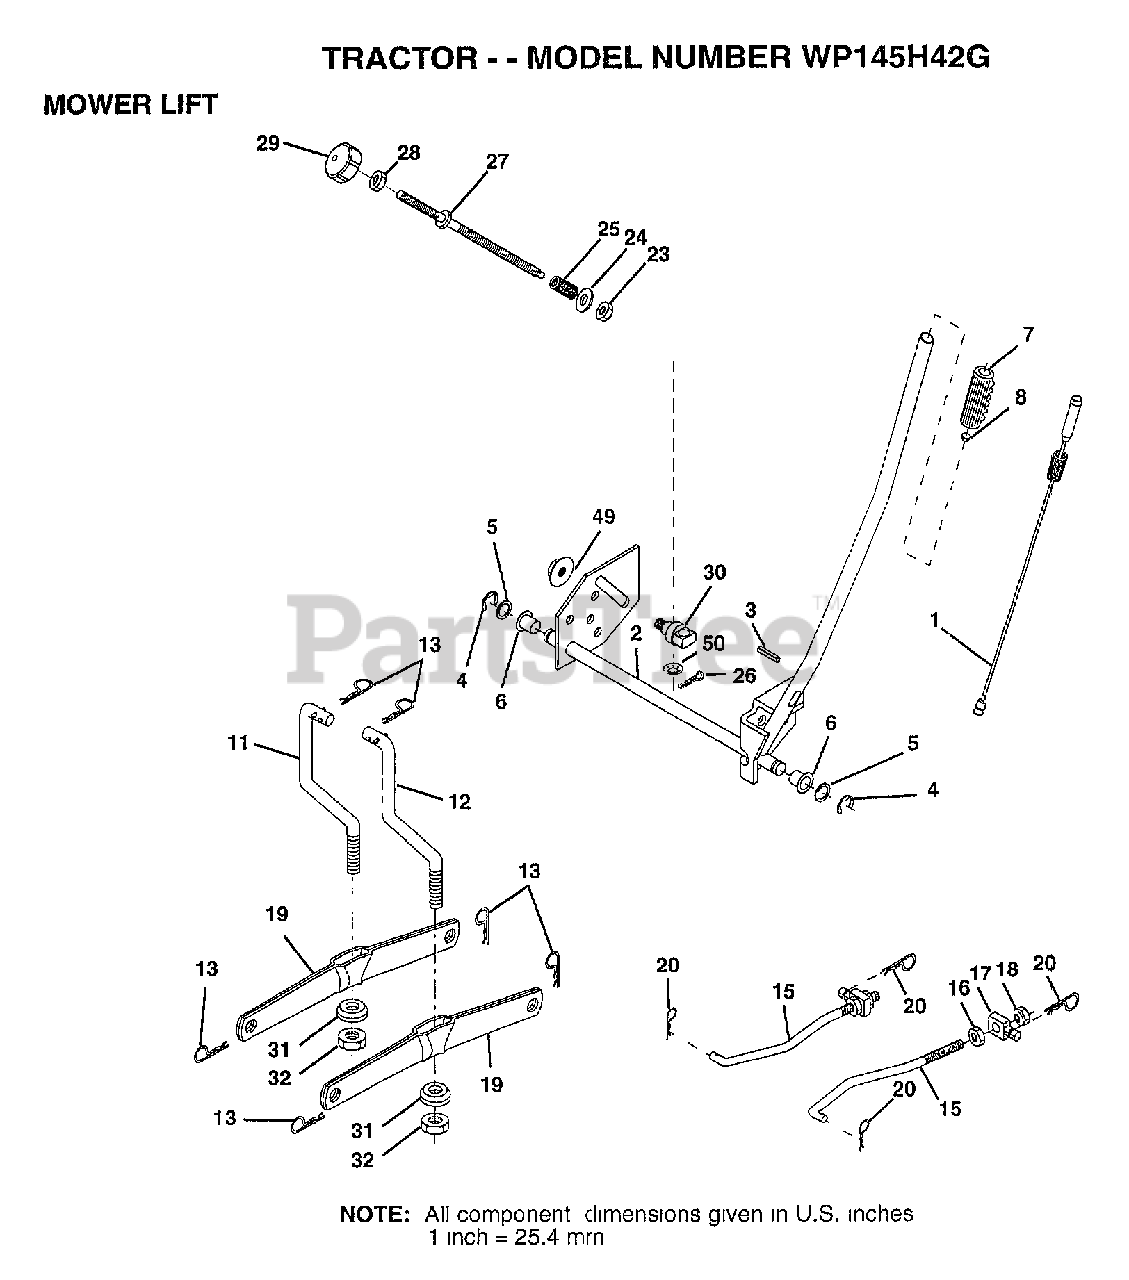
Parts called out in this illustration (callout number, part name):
1	WIRE.ASM.INNER.SP
2	"SHAFT AMS LIFT,RH"
3	PIN GROOVE
5	WASHER
6	NYLON BEARING
7	GRIP
15	LINK.FRONT
16	NUT
17	TRUNION
18	NUT LTV
19	ARM SUSP REAR
20	RETAINER SPRING
23	NUT T
24	WASHER
25	SPRING.COMP.INF.H
27	ROD.ADJ.LIFT
28	NUT
29	KNOB INF 3/8-16
30	TRUNNION
31	BEARING PVT LH
32	NUT.CROWNLOCK.3/8
49	NUT.HXFLG.LOCK.
50	NUT PUSH M
